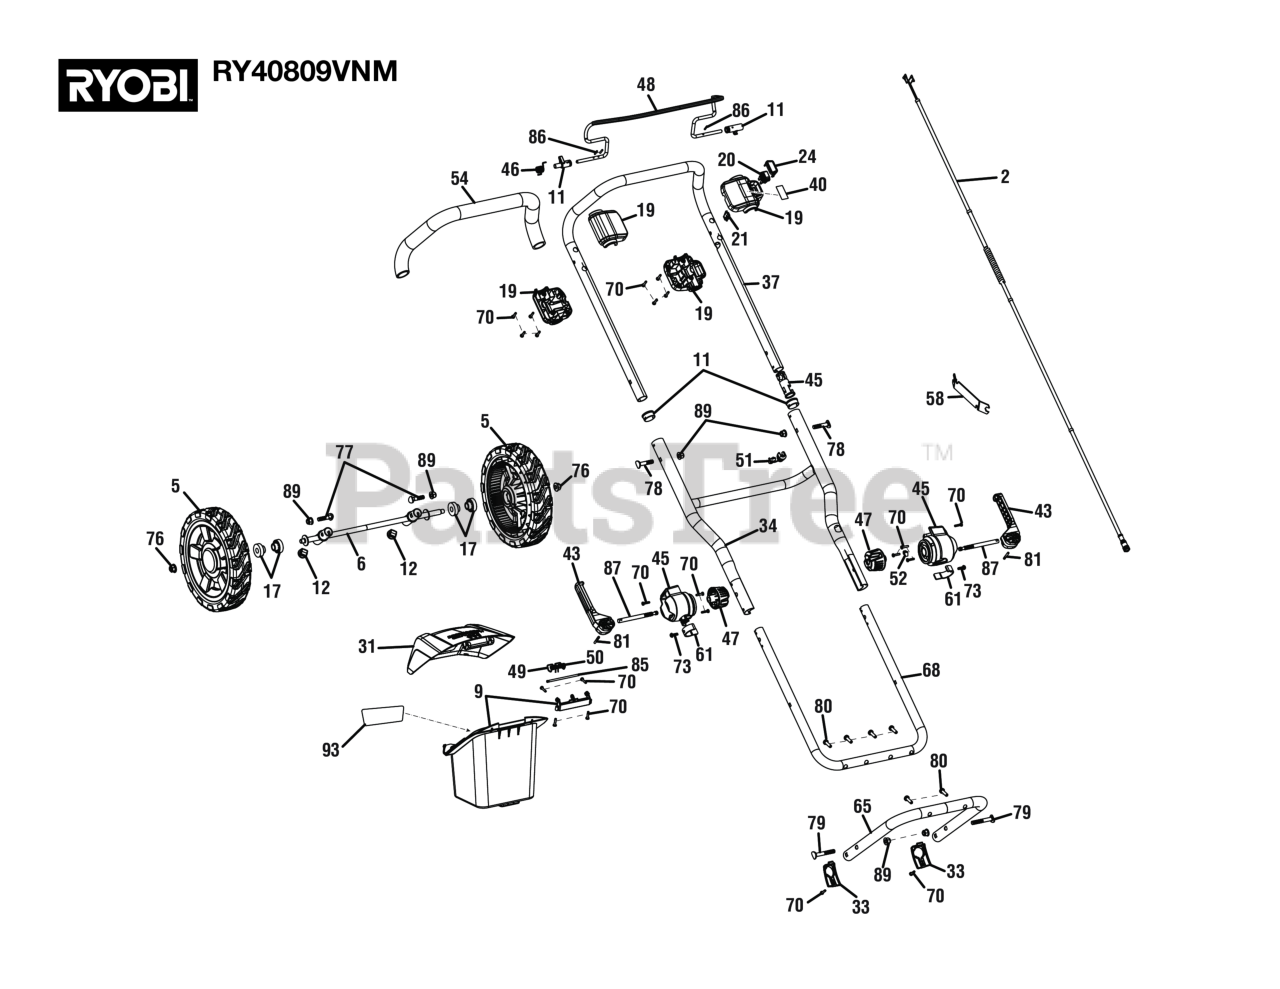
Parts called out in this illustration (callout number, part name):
2	Electrical Wire Assembly
5	10 in. Wheel
6	Lower Support Tube and Axle Assembly
9	Battery Box With Label
11	Actuator and End Bushing Assembly
17	Wheel Spacer
19	Handle Latch Housing Assembly With Label
20	Center Switch
21	Micro Switch
24	Saftey Button
31	Battery Cover
33	Tube Exit Cover Assembly
34	Lower Handle Tube
37	Top Handle Tube
40	Starting Instructions Label
43	Cam Latch
45	Knuckle and Cable Gland Assembly
46	Torsion Spring
47	Knuckle Knob
48	Metal Wire Trigger
49	Torsion Spring For Battery Cover (Left)
50	Torsion Spring For Battery Cover (Right)
51	Cable Grommet
52	Wire Clamp
54	Rubber Foam Tube
61	Handle Limiter Spring
65	Bracing Tube
68	Mount Body Tube
70	Screw (M4 x 18 mm, T20 Torx Pan Hd. S.T.)
73	Screw (M5 x 16 mm, T25 Torx Pan Hd.)
76	Lock Nut (3/8-16, Flange)
77	Screw (M8 x 36 mm)
78	Screw (M8 x 42 mm)
79	Screw (M8 x 62 mm, Special Hd.)
80	Screw (1/4-15 x 3/4 in., T30 Torx Pan Hd.)
81	Cam Lever Dowel (4 mm)
85	Battery Cover Pin
86	Spring Pin (3 x 16 mm)
87	Dual Thread Pin
89	Flange Lock Nut (M8 x 1.25 mm)
93	Battery Notice Label
